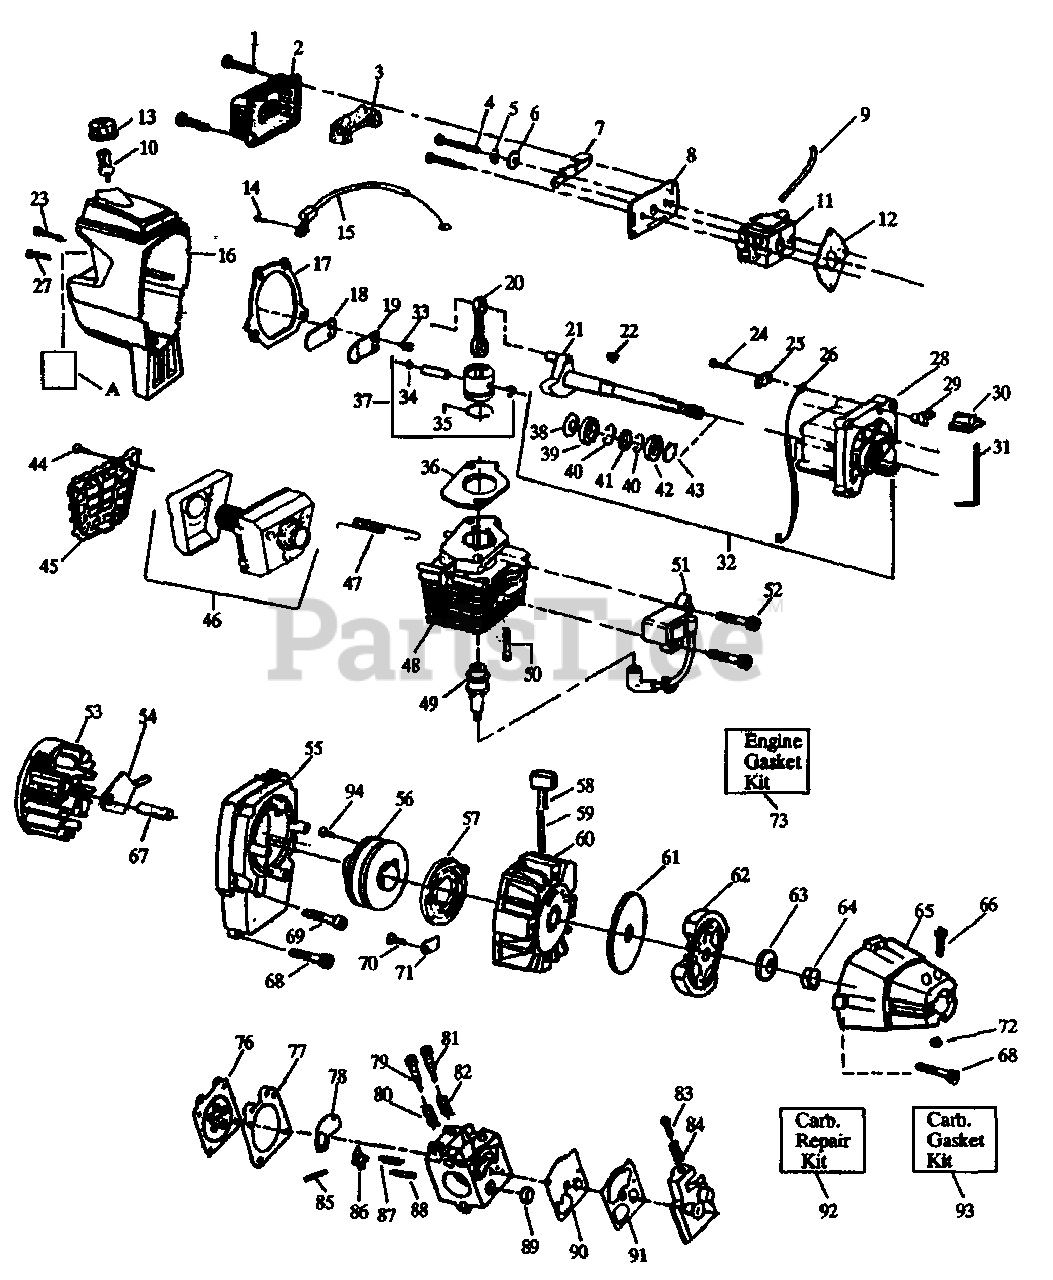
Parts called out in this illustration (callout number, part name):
2	Air Filter Cover
3	Air Filter
5	Spacer
6	Wave Washer
7	Choke Shutter
8	Air Filter Plate
9	Fuel Line Kit
10	Fuel Pick-up Ass'y.
11	Carburetor (WA-199)
12	Carburetor Gasket
13	Fuel Cap Ass'y.
15	Throttle Cable Ass'y.
16	Shroud & Tank Ass'y.
17	Gasket
20	Connecting Rod Ass'y.
21	Crankshaft Ass'y.
22	Flywheel Key
25	Kill Switch Insulator
28	Crankcase Ass'y.
29	Kill Switch Ramp
30	Kill Switch Button
31	Kill Switch Spring
32	Crankcase & Crankshaft Ass'y.
33	Screw
34	Piston Pin Retainer
35	Piston Ring
36	Cylinder Gasket
37	Piston Kit
39	Inner Bearing
40	Retaining Ring
41	Crankshaft Seal
42	Outer Bearing
43	Crankshaft Retaining Ring
45	Muffler Guard
46	Muffler Kit
47	Muffler Spring
48	Cylinder
49	Spark Plug
51	Ignition Module Kit
52	Screw
53	Flywheel Ass'y.
54	Flywheel Counterweight
55	Fan Housing
56	Starter Pulley
57	Starter Spring
58	Starter Handle
60	Pulley Housing Ass'y.
61	Clutch Washer
65	Clutch Housing
71	Pulley Retainer
73	Engine Gasket Kit
76	Metering Diaphragm
77	Metering Diaphragm Gasket
78	Circuit Plate Gasket
79	Hi Speed Needle
80	Hi Speed Needle Spring
81	Idle Needle
82	Idle Needle Spring
83	Idle Speed Screw
84	Idle Speed Spring
85	Metering Lever Pin
86	Metering Lever
87	Metering Lever Spring
88	Inlet Needle Valve
89	Inst Screen
90	Pump Diaphragm
91	Pump Gasket
92	Carb. Kwik Repair Kit
93	Carb. Gasket/Diaphragm Kit
94	Screw
A	Instruction Decal
